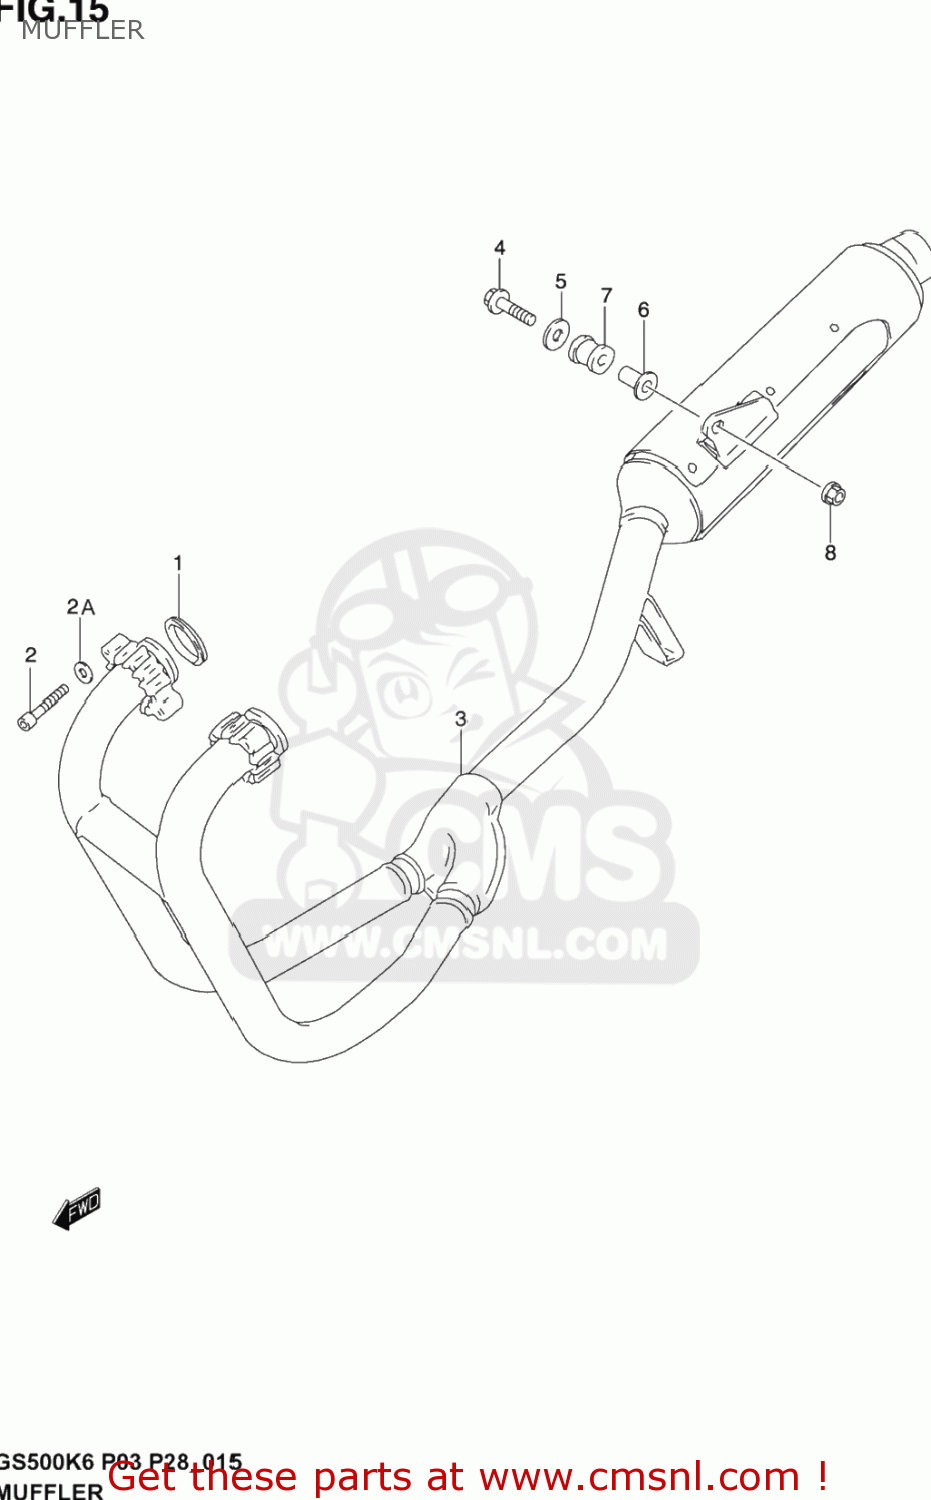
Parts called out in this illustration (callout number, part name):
1	GASKET,EXHAUST PIPE (NAS)
2	BOLT
2A	WASHER
3	MUFFLER
4	BOLT(8X40)
5	WASHER(8.5X28X1.6)
6	SPACER(8.6X12X24.2)
7	CUSHION
8	NUT
